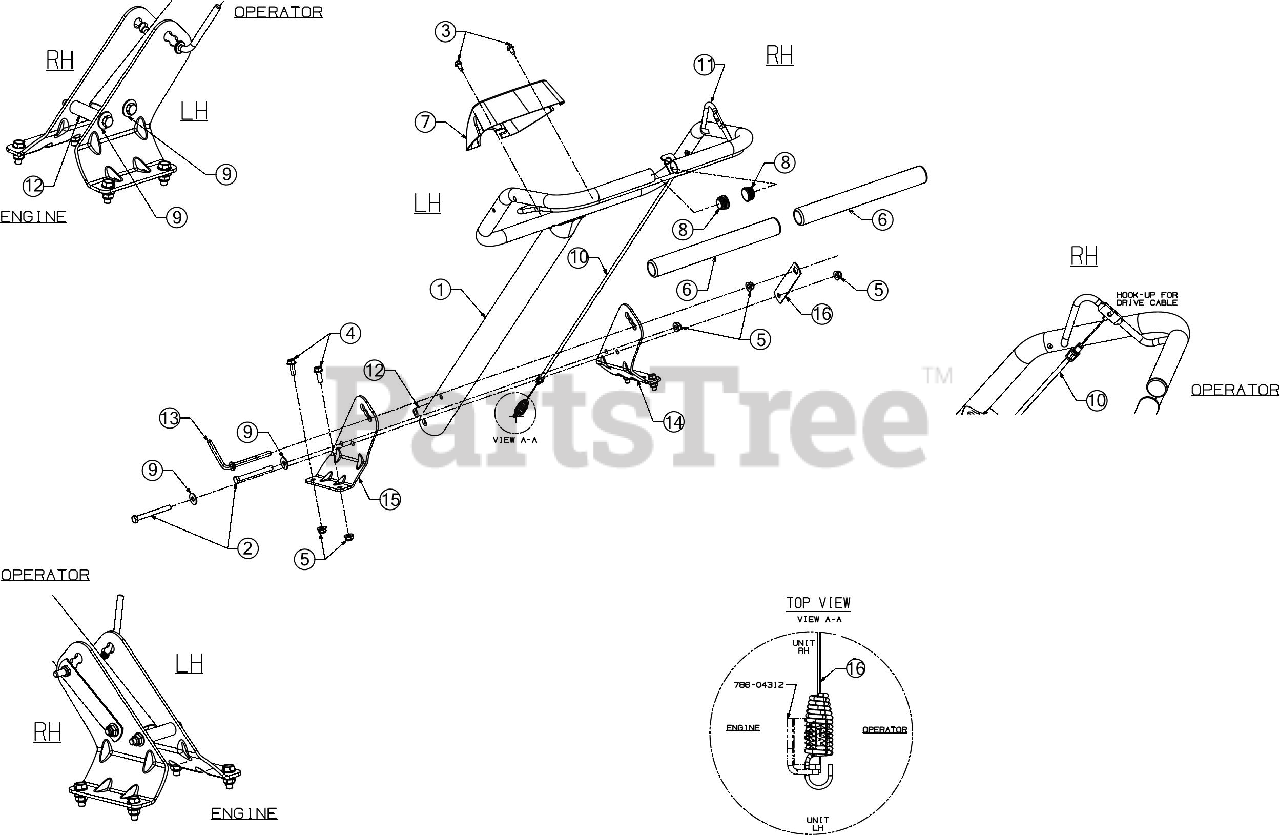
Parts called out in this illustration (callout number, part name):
1	UPPER HANDLE ASSEMBLY
2	HEX SCREW 5/16-18 x 3.00
3	SCREW 1/4-20 X.500
4	SCREW 5/16-18 x .875 GR5
5	FLANGE LOCK NUT 5/16-18
6	FOAM GRIP .970 x 11.0
7	HANDLE COVER W/O SWITCH HOLE
9	BELL WASHER .337 X.867 x .057
10	FORWARD CABLE
13	CRANK ADJUST HANDLE
14	HANDLE BRACKET (RH)
15	HANDLE BRACKET (LH)
16	RETURN BRACKET
